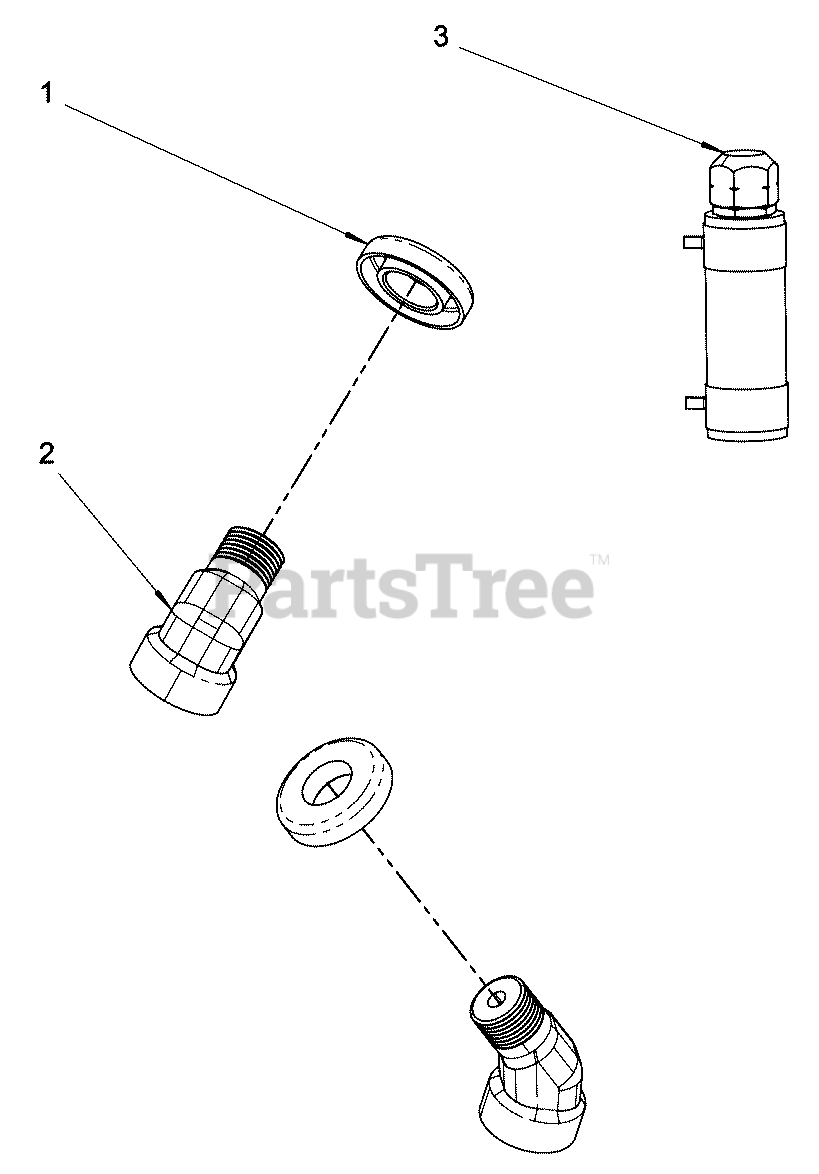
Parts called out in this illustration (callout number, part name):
1	ADAPTER, FR/PLUG
2	PIPE, STR ELBOW
3	CAP, W/PMP HOSE
